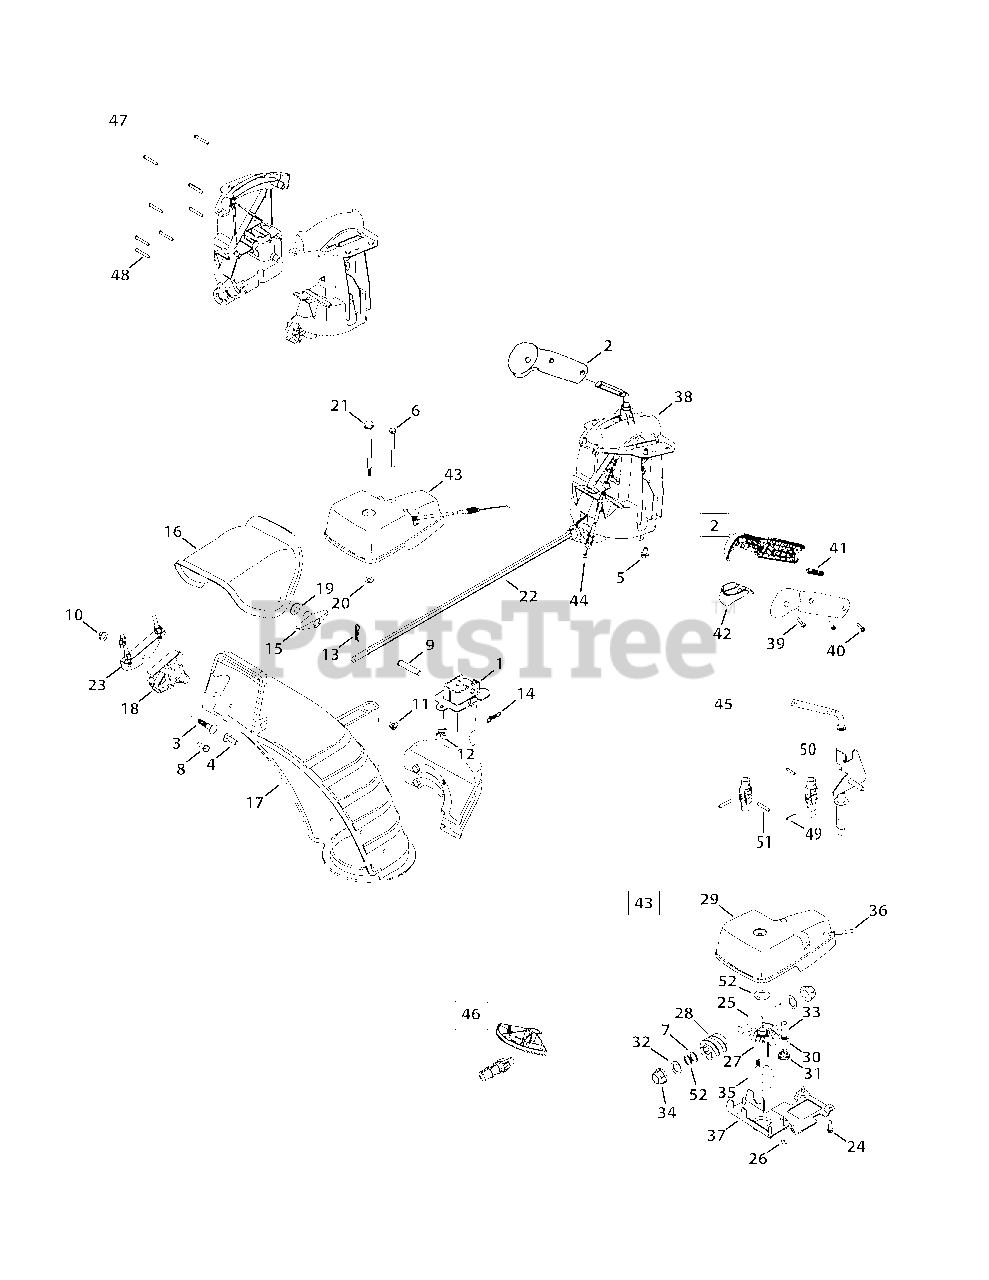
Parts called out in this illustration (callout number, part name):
1	Chute Support Bracket (lrg. block)
2	Chute Control, 4-Way
3	Bolt, Carriage, 5/16-18 x 1.50, 4-Way
4	Bolt, Carrier, 5/16-18 x 1.00
5	Screw, Hi-Lo, 1/4-15 x 0.50
6	Hex Head Screw, 1/4-20 x 3.00
7	Shim Washer, .632 x 1.00 x .010
8	Screw, Hi-Lo, 1/4-15 x 0.750
9	Clevis Pin, 3/8 x 1.87
10	Nut, Flange Lock, 5/16-18
11	Nut, Flange Lock, 1/4-20
12	Wing Nut, 1/4-20
13	Internal Cotter Pin
14	Bow-Tie Cotter Pin
15	Wing Knob, 5/16-18
16	Chute, Upper, 4-Way
17	Chute, Lower
18	Cable Guide, Chute Tilt
19	Washer, Flat, .349 x .879
20	Washer, Flat, .25 x .630
21	Screw, Shoulder, .312 x 3.5 x 1/4-20
22	Chute Rod, 3/8 Hex
23	Cable Bracket
24	Screw, 12-16 x .75
26	Hexlock Nut, 1/4-28
27	Gear, 14 T
28	Worm
29	Gear Cover
31	Torsion Spring, .721 ID x .474
32	Washer, Flat, .625 x 1.0 x .067
33	Screw, Shoulder, .34 x .95 x 1/4-28
34	Hex Bearing
35	Flange Bearing
38	Chute Control, 4-Way
39	Screw, #8 x 1.00
40	Screw, 8-32 x .750
41	Joystick Plug
42	Joystick Trigger
43	Chute Rotation Gearbox
44	4-Way Cable
44	Cable Clip
45	Shift Assembly, 4-Way
46	Gear Set Assembly
47	Handle Housing Assembly, 4-Way
48	Screw, #8-18 x 1.250
50	Block, Asm Joint
51	Pin, Roll
52	Shim Washer, .63 x 1.00 x .020
